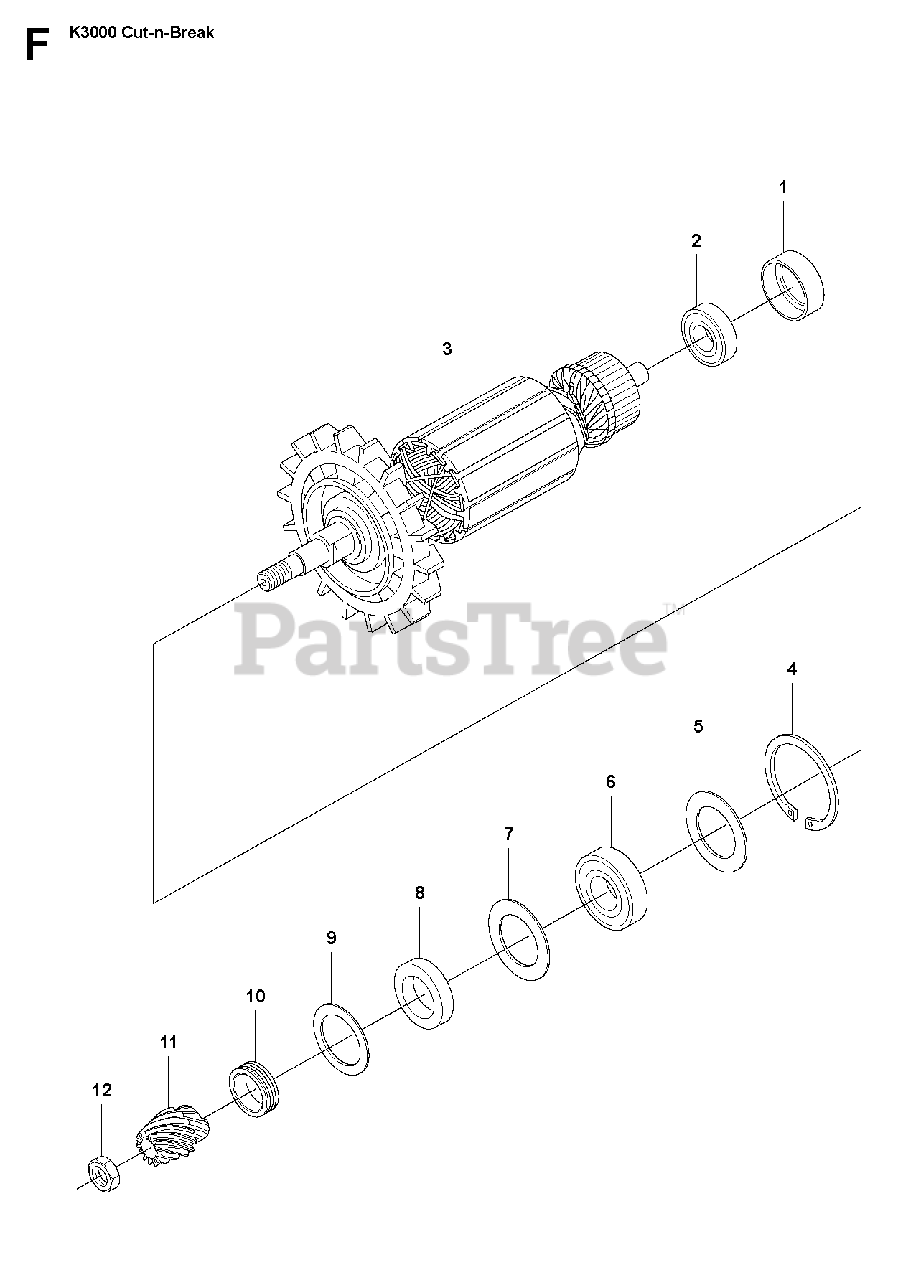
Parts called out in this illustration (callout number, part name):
1	RUBBER BUSHING
3	ARMATURE100 - 120V
3	ARMATURE230V
6	BALL BEARING
12	HEXAGON NUT
